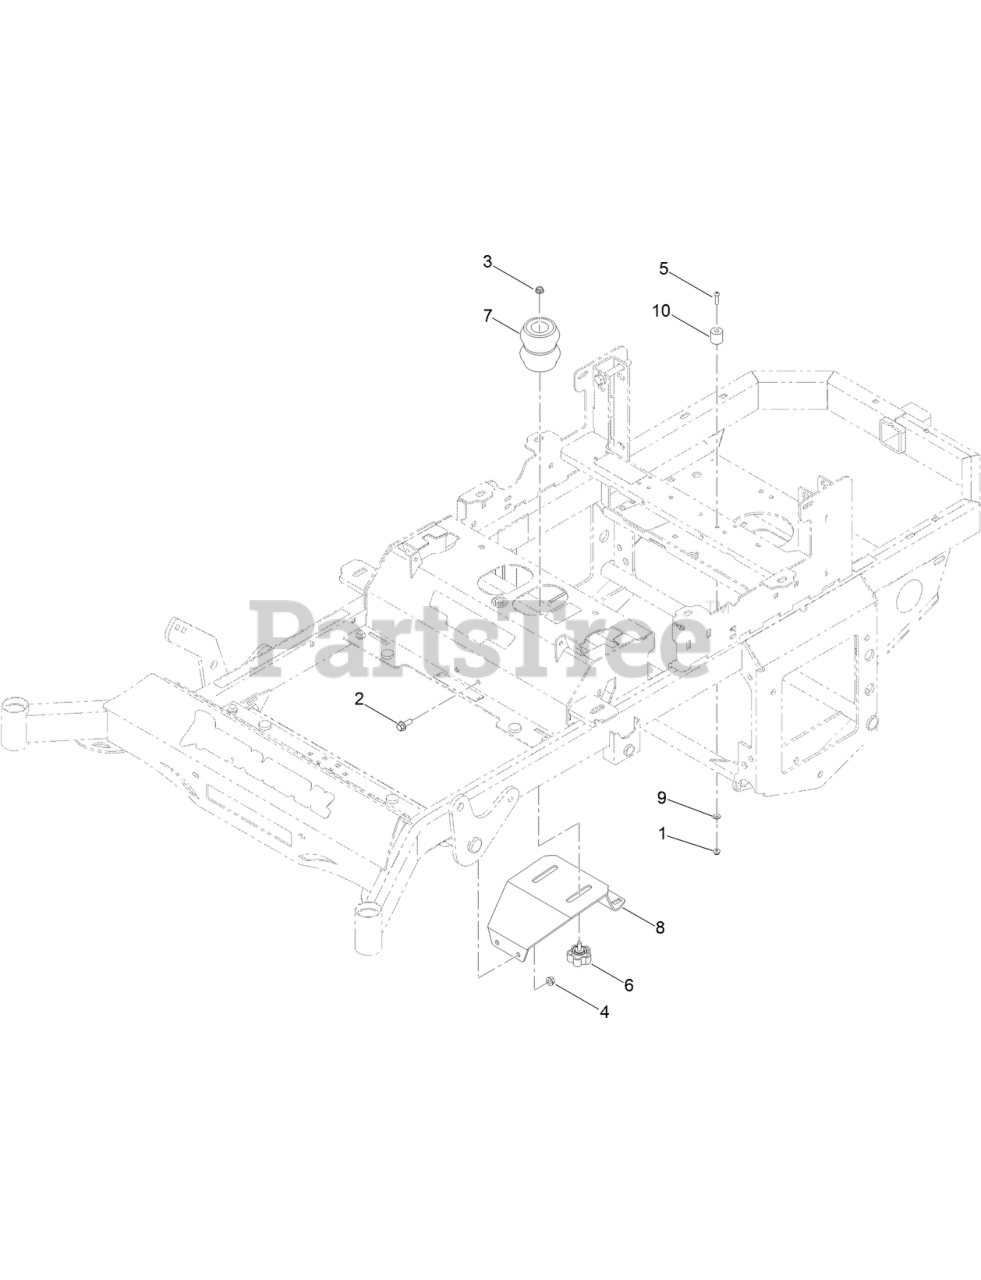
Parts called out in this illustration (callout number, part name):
1	NUT-HF
2	SCREW-HHF
4	3/8-16 HEX FLANGE NUT W/SERR ZINC YELLOW
5	1/4-20 X 1 BUTTON SOCKET C/S 18-8 SS
6	5/16-18X3/4 SL 5-LOBE MALE KNOB 1.90 DIA
7	SRT RR SUSP AND SEAT FT ELASTOMER TCB-3
8	MWR SEAT SUSP BRKT (SRT) PAINTED
9	WASHER-FLAT
10	HOOD REST RUBBER BUMPER
